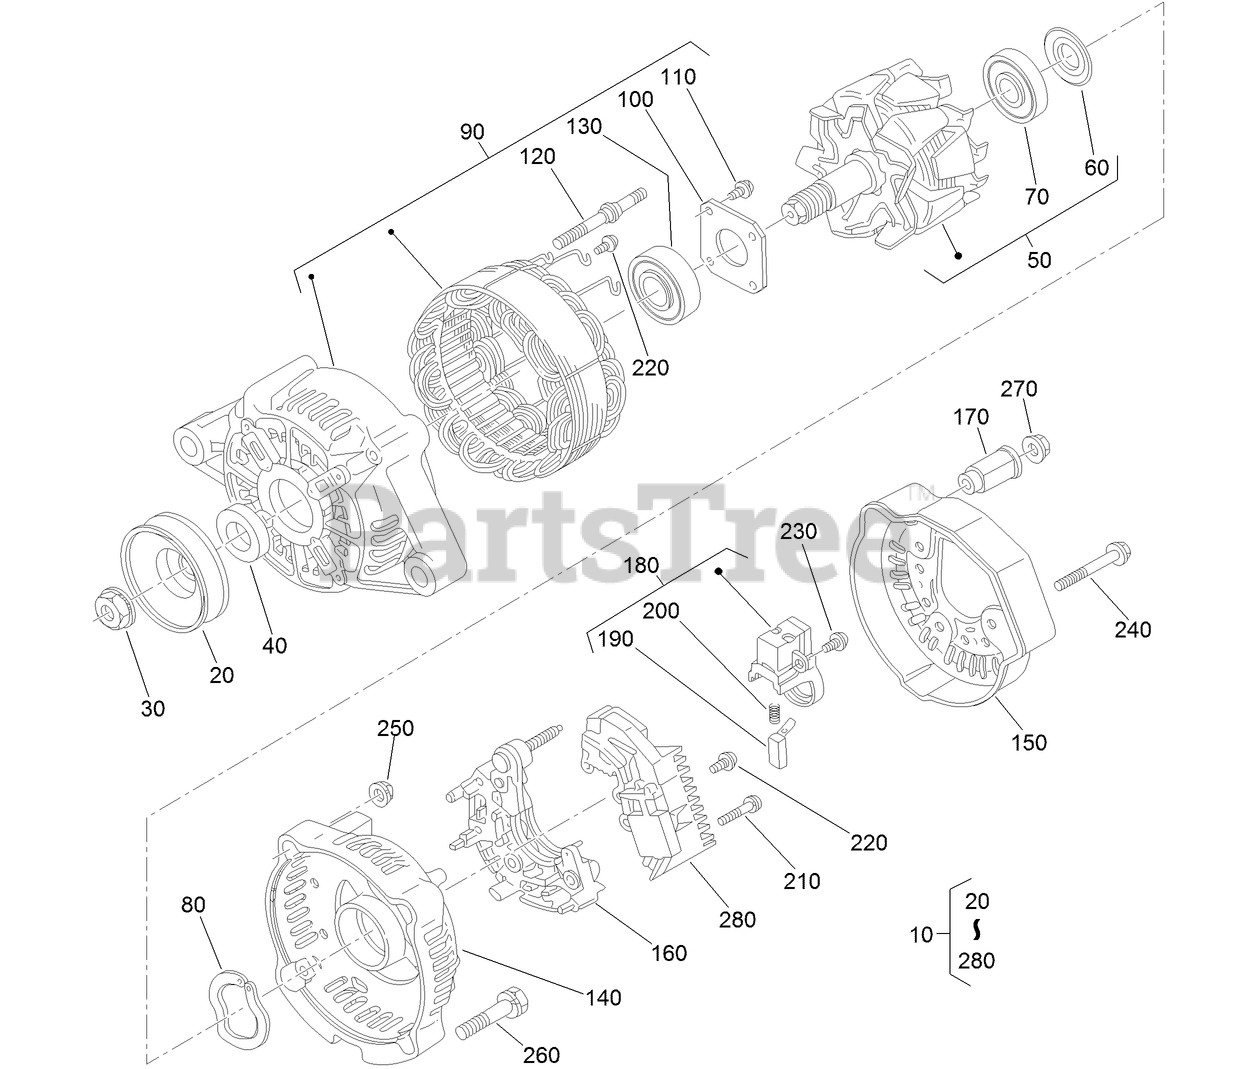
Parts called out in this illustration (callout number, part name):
10	ALTERNATOR
20	PULLEY-DYNAMO
40	COLLAR
50	ROTOR ASM
60	COVER-BEARING
70	BEARING-BALL
80	WASHER-THRUST
90	FRAME, DRIVE END
100	PLATE-RETAINER
110	SCREW-HEAD, ROUND
120	BOLT-THROUGH
130	BEARING-BALL
140	FRAME-END
150	COVER-END
160	RECTIFIER ASM
170	BUSHING-INSULATION
180	BRUSH HOLDER ASM
190	BRUSH
200	SPRING-BRUSH
210	SCREW-HEAD, ROUND
220	SCREW-HEAD, ROUND
230	SCREW-HEAD, ROUND
280	REGULATOR ASM
